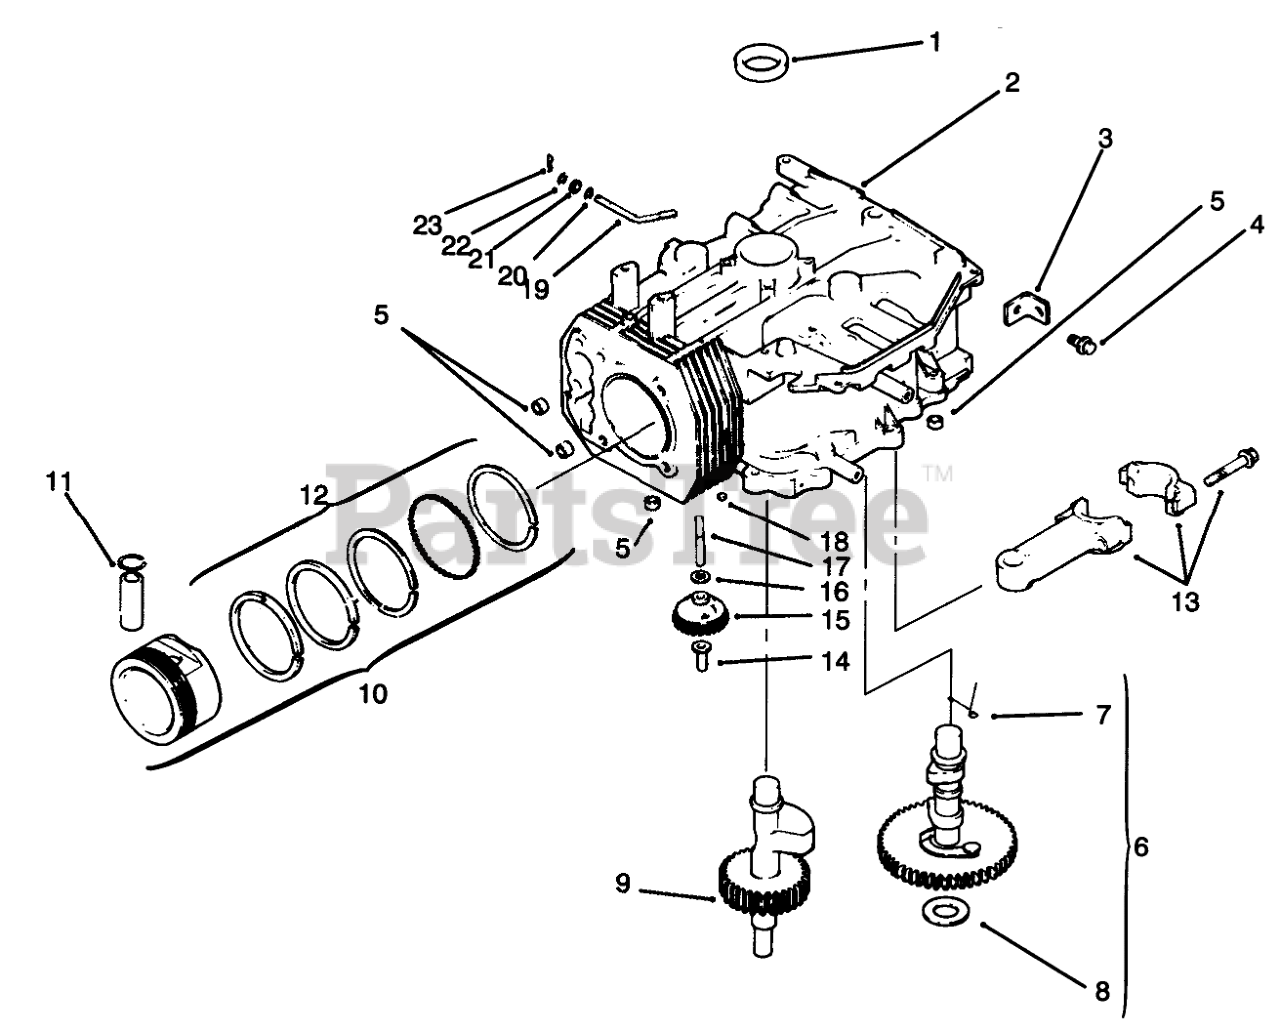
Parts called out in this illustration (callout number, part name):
1	Seal-Crankshaft (Only On: 72042, 72043, 72062, 72063)
3	Strap-Lifting (Only On: 72042, 72043, 72062, 72063)
4	Screw M8x1.25x22 (Only On: 72042, 72043, 72062, 72063)
5	Dowel-Locating (Only On: 72042, 72043, 72062, 72063)
6	Kit-Camshaft INCL 7-8 (Only On: 72042, 72043, 72062, 72063)
7	Spring-Actuating (Only On: 72042, 72043, 72062, 72063)
8	Shim-Camshaft A/R (Only On: 72042, 72043, 72062, 72063)
9	Shaft-Balance (Only On: 72042, 72043, 72062, 72063)
10	Piston ASM STD INCL 11-12 (Only On: 72042, 72043, 72062, 72063)
10	Piston ASM .25 INCL 11-12 (Only On: 72042, 72043, 72062, 72063)
10	Piston ASM .50 INCL 11-12 (Only On: 72042, 72043, 72062, 72063)
11	Retainer-Piston Pin (Only On: 72042, 72043, 72062, 72063)
12	Ring Set STD (Only On: 72042, 72043, 72062, 72063)
12	Ring Set .25 (Only On: 72042, 72043, 72062, 72063)
12	Ring Set .50 (Only On: 72042, 72043, 72062, 72063)
13	Connecting Rod STD (Only On: 72042, 72043, 72062, 72063)
13	Connecting Rod .25 (Only On: 72042, 72043, 72062, 72063)
14	Pin-Governor Regulating (Only On: 72042, 72043, 72062, 72063)
15	Gear-Governor ASM (Only On: 72042, 72043, 72062, 72063)
16	Washer-Governor (Only On: 72042, 72043, 72062, 72063)
17	Shaft-Governor Gear (Only On: 72042, 72043, 72062, 72063)
18	Plug-Cup (Only On: 72042, 72043, 72062, 72063)
19	Shaft-Governor Cross (Only On: 72042, 72043, 72062, 72063)
20	Washer-Governor Shaft (Only On: 72042, 72043, 72062, 72063)
21	Seal-Governor Shaft (Only On: 72042, 72043, 72062, 72063)
22	Washer-Flat (Only On: 72042, 72043, 72062, 72063)
23	Pin-Governor Hitch (Only On: 72042, 72043, 72062, 72063)
